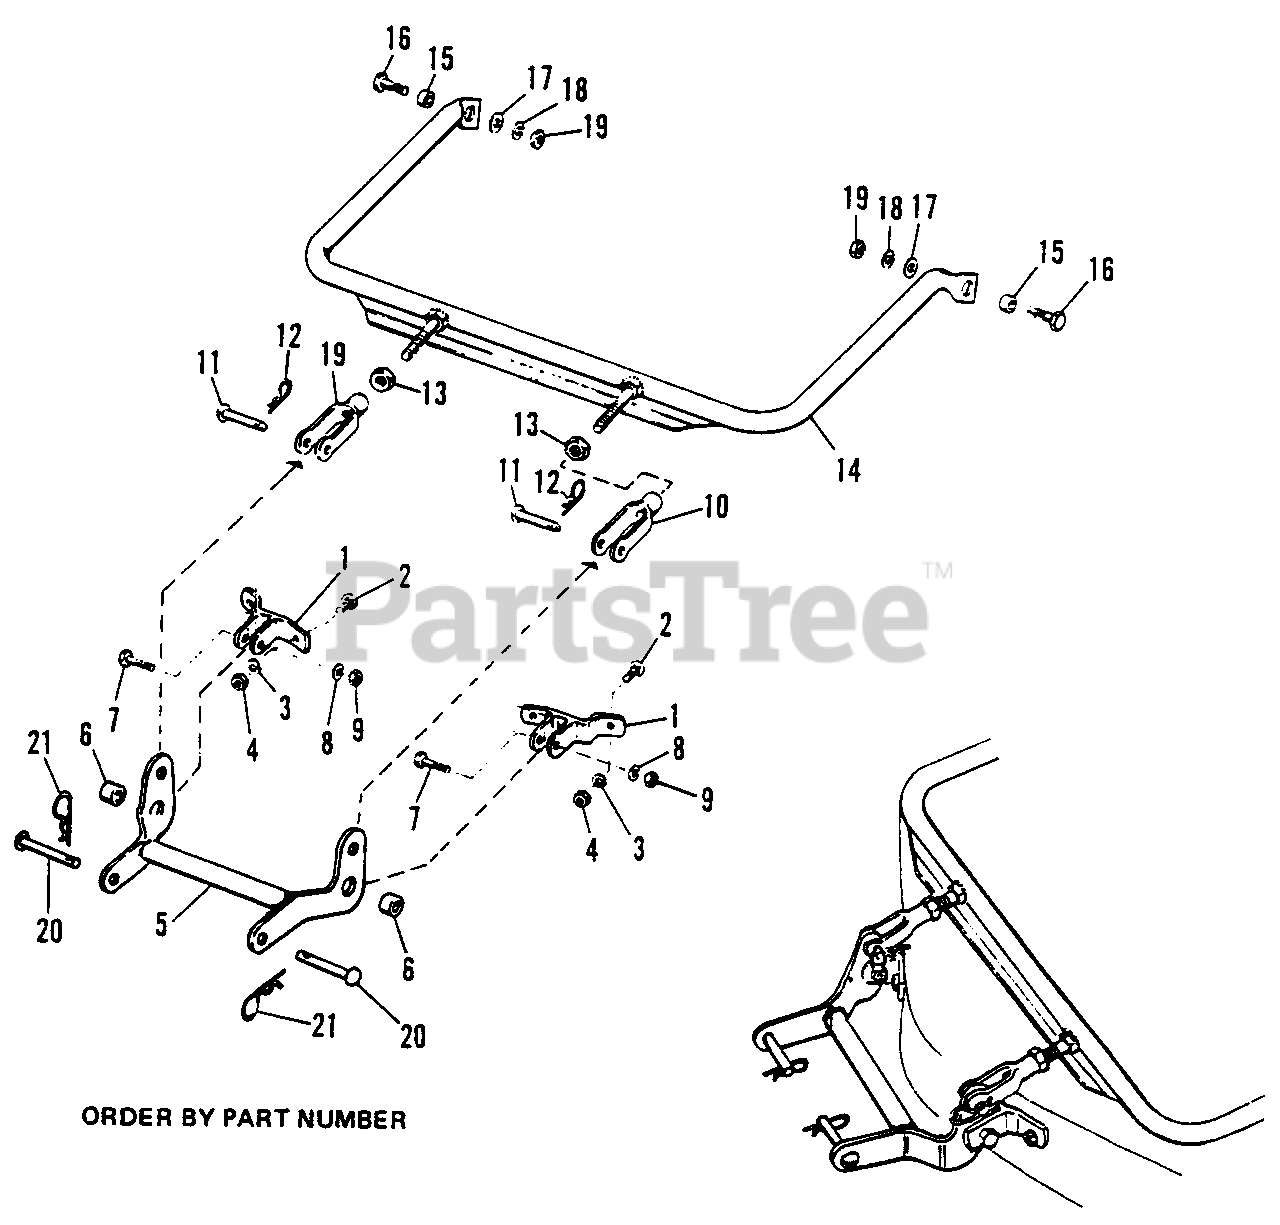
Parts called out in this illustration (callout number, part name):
1	Front Bracket Assembly
2	Carriage Bolt, 3/8"-16 x 1-1/4"
3	Lockwasher, 3/8"
4	Full Hex Nut, 3/8"-16
5	Rocker Arm
7	Hex Capscrew, 1/2"-13 x 1-1/4"
8	Lockwasher, 1/2"
9	Full Hex Nut, 1/2"-13
10	End Adj. Yoke
12	Spring Clip
13	Hex Jam Nut, 1/2"-20
14	Bail Assembly
16	Hex Capscrew, 1/2"-13 x 1-1/4"
17	Plain Washer, 7/16"
18	Lockwasher, 1/2"
19	Full Hex Nut, 1/2"-13
20	Pin
21	Safety Clip
